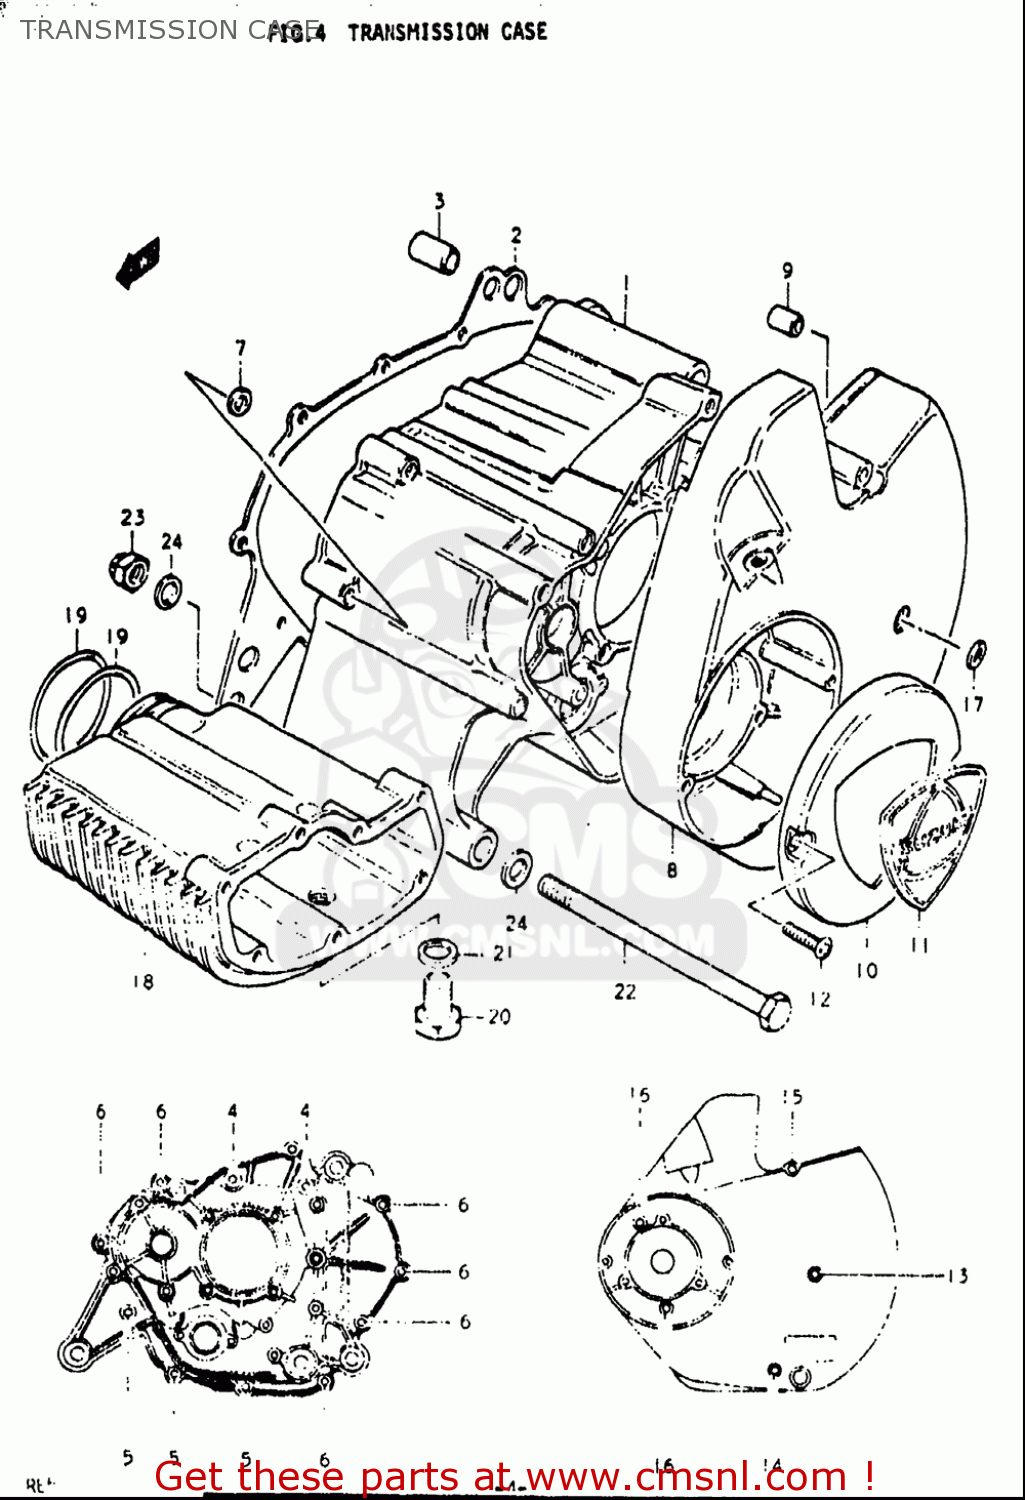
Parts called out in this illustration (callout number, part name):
3	PIN
7	WASHER
9	PIN
12	SCREW
15	BOLT
17	WASHER
20	PLUG
21	GASKET(14X19.2X2) (NAS)
22	BOLT(10X120)
23	NUT
24	WASHER
